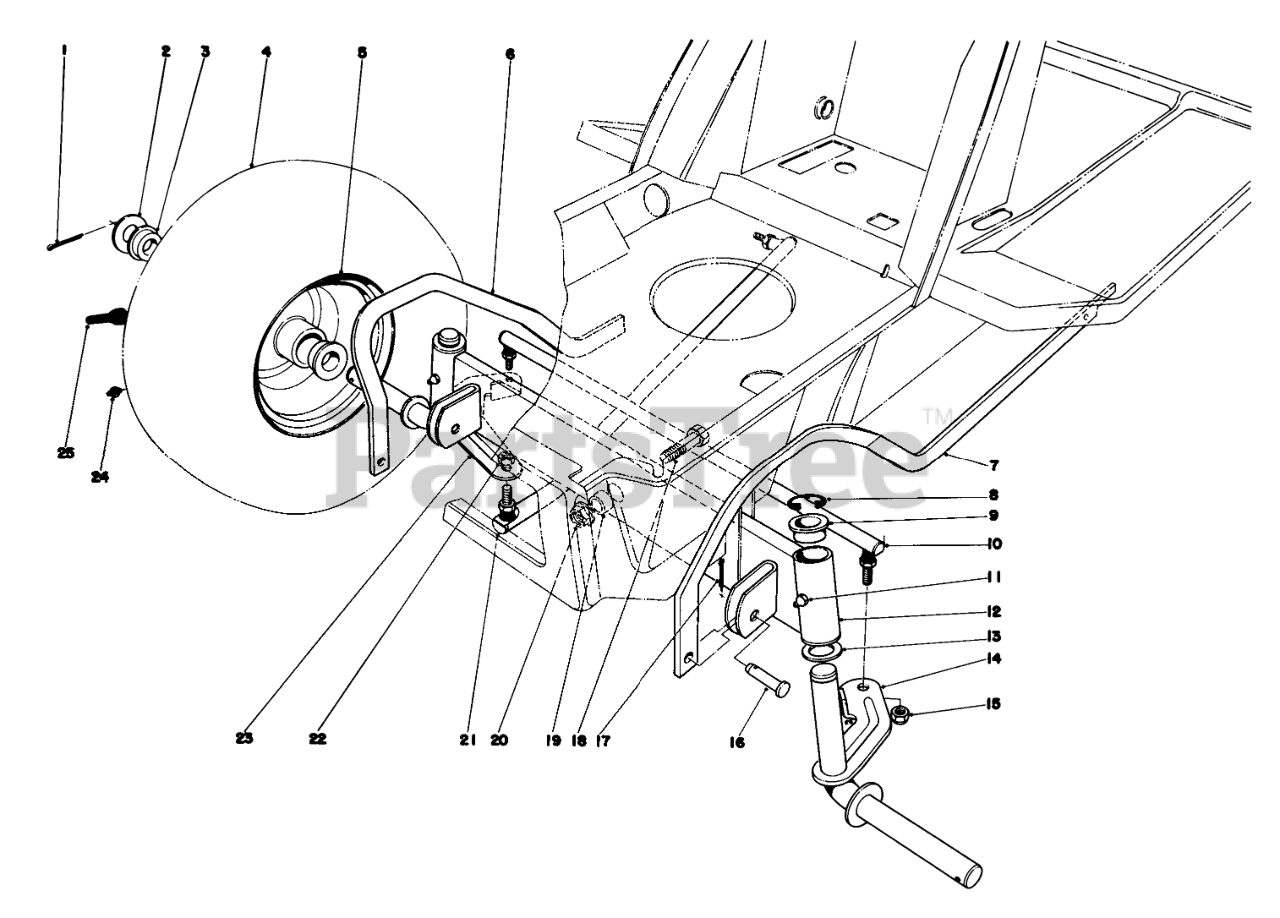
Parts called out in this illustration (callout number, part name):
1	PIN-COTTER
2	WASHER-PLAIN
3	WHEEL BSHG
4	Tire
6	RH DECK PARALLEL LINK R
7	LH DECK PARALEL LNKR
8	E-RING
9	BEARING-FLANGE
10	Tie Rod Steering
11	GREASE FITTING
12	FRONT AXLE WA
13	WASHER-THRUST
14	Spindle L.H.
15	NUT-LOCK NI
16	PIN-CLEVIS
17	PIN-COTTER
18	SCREW-HH
19	SPACER-AXLE, FRONT
20	NUT-HF
21	Steering Arm
22	Nut
23	SPINDLE WA RH B
24	FITTING-GREASE
25	STEM-VALVE
